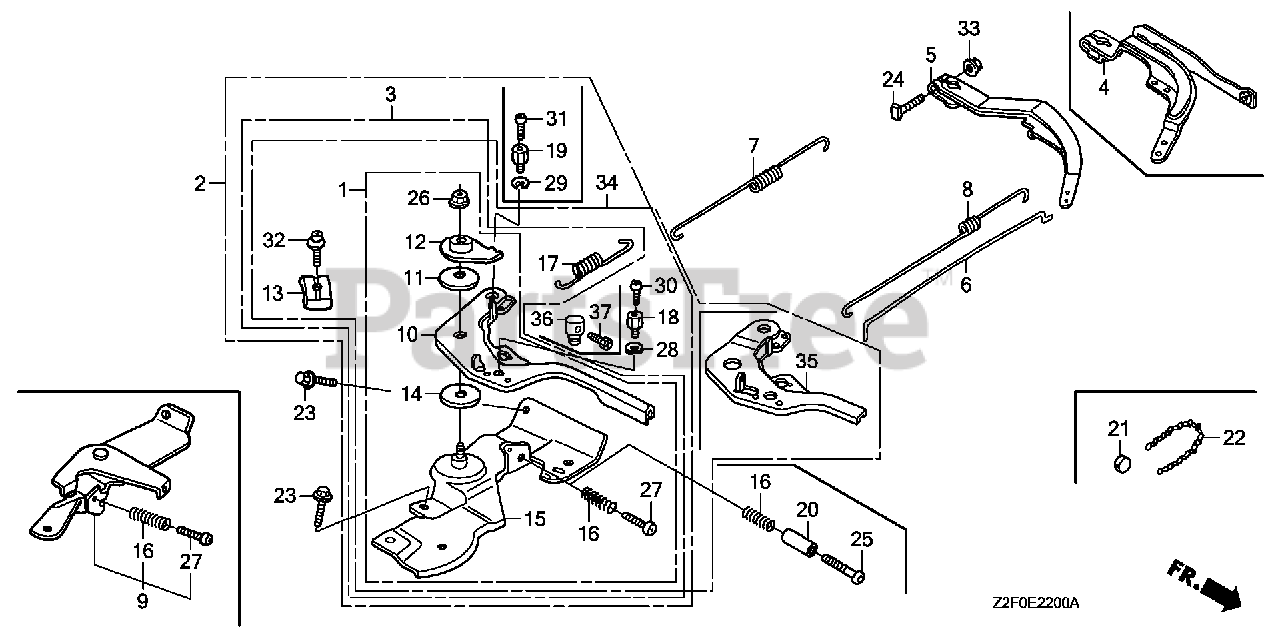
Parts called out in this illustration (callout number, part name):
3	CONTROL ASSY. (REMOTE)
5	ARM, GOVERNOR
6	ROD, GOVERNOR
7	SPRING, GOVERNOR
8	SPRING, THROTTLE RETURN
10	LEVER, CONTROL
11	SPRING, LEVER
12	WASHER, CONTROL LEVER
13	HOLDER, CABLE
14	SPACER, CONTROL LEVER
15	BASE, CONTROL (REMOTE)
16	SPRING, CONTROL ADJUSTING
17	SPRING, CABLE RETURN
23	BOLT, FLANGE (6X12) (CT200)
24	BOLT, GOVERNOR ARM
26	NUT, SELF-LOCK (6MM)
27	SCREW, PAN (5X25)
32	SCREW, PAN (5X16)
33	NUT, FLANGE (6MM)
